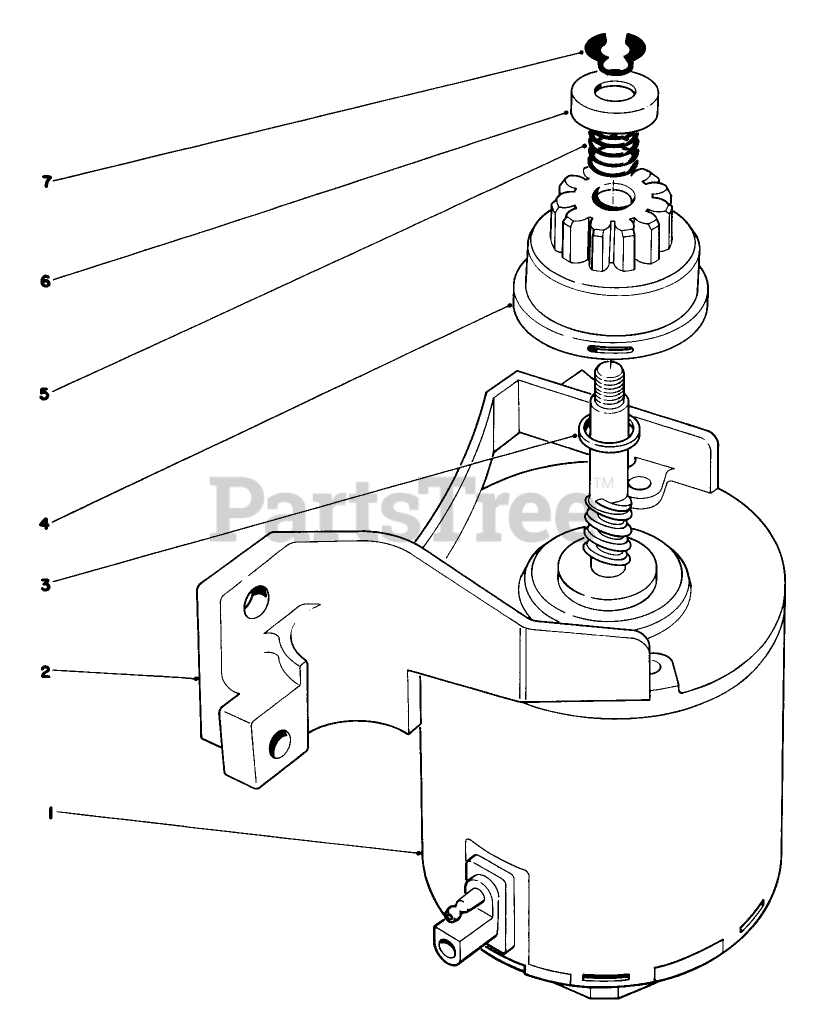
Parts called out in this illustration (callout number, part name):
1	END FRAME W/BRUSH
2	BRKT END FRAME
3	SPACER
4	PINION ASM
5	COMPRESSION SPRING
6	PINION STOP
7	RING-RETAINING
